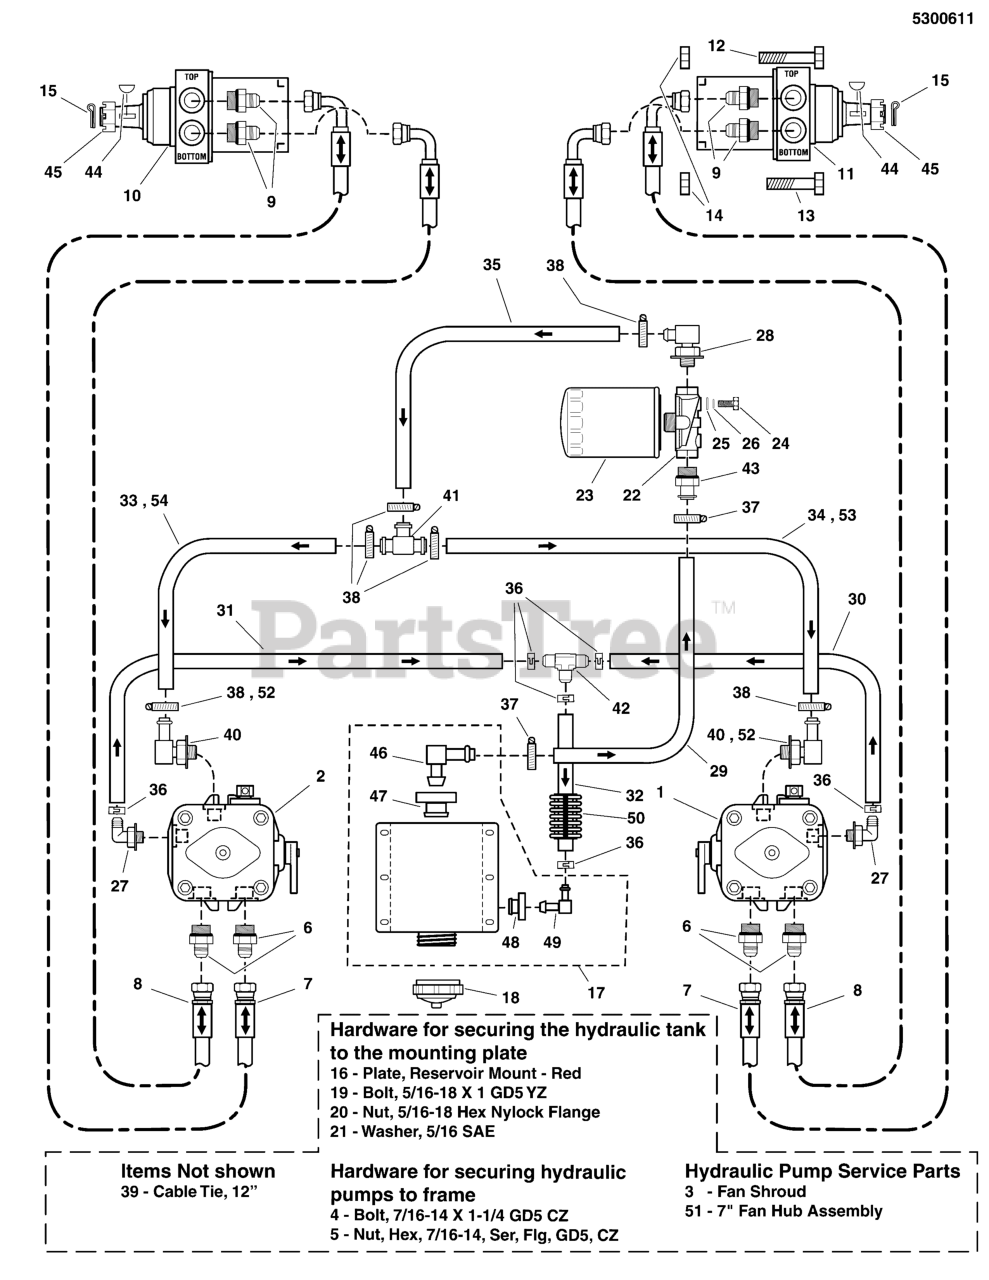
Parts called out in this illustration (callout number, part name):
1	PUMP, 16CC, PR-2KBQ-GV1F-XXXX
2	PUMP, 16CC, PR-2HBQ-GV1F-XXXX
3	FAN SHROUD (SV)
4	BOLT, 7/16-14 X 1-1/4 GD5 YZ
5	NUT, HEX, 7/16-14, SER, FLG, GD5, YZ
6	FITTING, #8 O-RING X #8 JIC, STR
7	HOSE ASSEMBLY (33)
8	HOSE ASSEMBLY, (29)
9	FITTING, #10 O-RING X #8 JIC, STR
10	WHEEL MOTOR, LH, 17.1 CI
11	WHEEL MOTOR, RH, 17.1 CI
12	BOLT, 1/2-13 X 2-1/2, NYLON PATCH
13	BOLT, 1/2-13 X 2-1/4" w/ Loctite Patch
14	NUT, 1/2-13 Square
15	PIN, COTTER, 1/8 X 1-1/4
16	PLATE, RESERVOIR MOUNT - RED
17	TANK, HYDRAULIC, ASSEMBLY
18	CAP, HYDRAULIC, SHIELDED VENT
19	BOLT, 5/16-18 X 1" GRD5 YZ
20	NUT, 5/16-18 HEX NYLOCK FLANGE NUT
21	WASHER, 5/16" SAE
22	FILTER HEAD, HYDRAULIC
23	FILTER, OIL
24	BOLT, 1/4"-20 X 3/4" GD5 YZ
25	WASHER, 1/4 SAE
26	WASHER, 1/4 LOCK
27	ADAPTER, 90 DEG. 9/16 - 3/8 BARB
28	FITTING, 9/16 O-RING-1/2" HOSE, 90 DEG
29	HOSE, 5/8" PUSH-ON, 18.00"
30	HOSE, 3/8" PUSH-LOCK, 11.00"
31	HOSE, 3/8" PUSH-LOCK, 30"
32	HOSE, 3/8" PUSH-LOCK, 28.00"
33	HOSE, 1/2" PUSH-ON, 28.00"
34	HYDRAULIC HOSE, Pump To Cooler
35	HOSE, 1/2" X 5.5" PUSH LOCK
36	CLAMP, Hose
37	CLAMP, #10 HOSE, STAINLESS
38	CLAMP, #6 HOSE, STAINLESS
39	TIE, SELF-LOCKING, 12"
40	FITTING, 1/2 HOSE TO 3/4 - 16 O-RING, 90
41	FITTING, BEADED TEE, 1/2 X 1/2 X 1/2, YZ
42	FITTING, TEE, 3/8" Hose
43	FITTING, STRAIGHT, HYD #12618
44	KEY, WOODRUFF, #1008, 5/16 X 1
45	NUT, CASTLE, 1-20
46	FITTING, ELBOW, 5/8" (SV)
47	GROMMET (SV)
48	BUSHING-FUEL TANK RED RUBBER
49	FITTING, ELBOW, 3/8" (SV)
50	WIRE LOOM, 5/8 ID, 6" LONG
51	7" FAN HUB ASSEMBLY, HYDROGEAR #70811
52	FITTING, EXTRA LG, 90, 1/2 TUBE - 3/4-16
53	HYDRAULIC HOSE, Cooler To Reservoir
54	HOSE, 1/2" PUSH-ON, 27.00"
